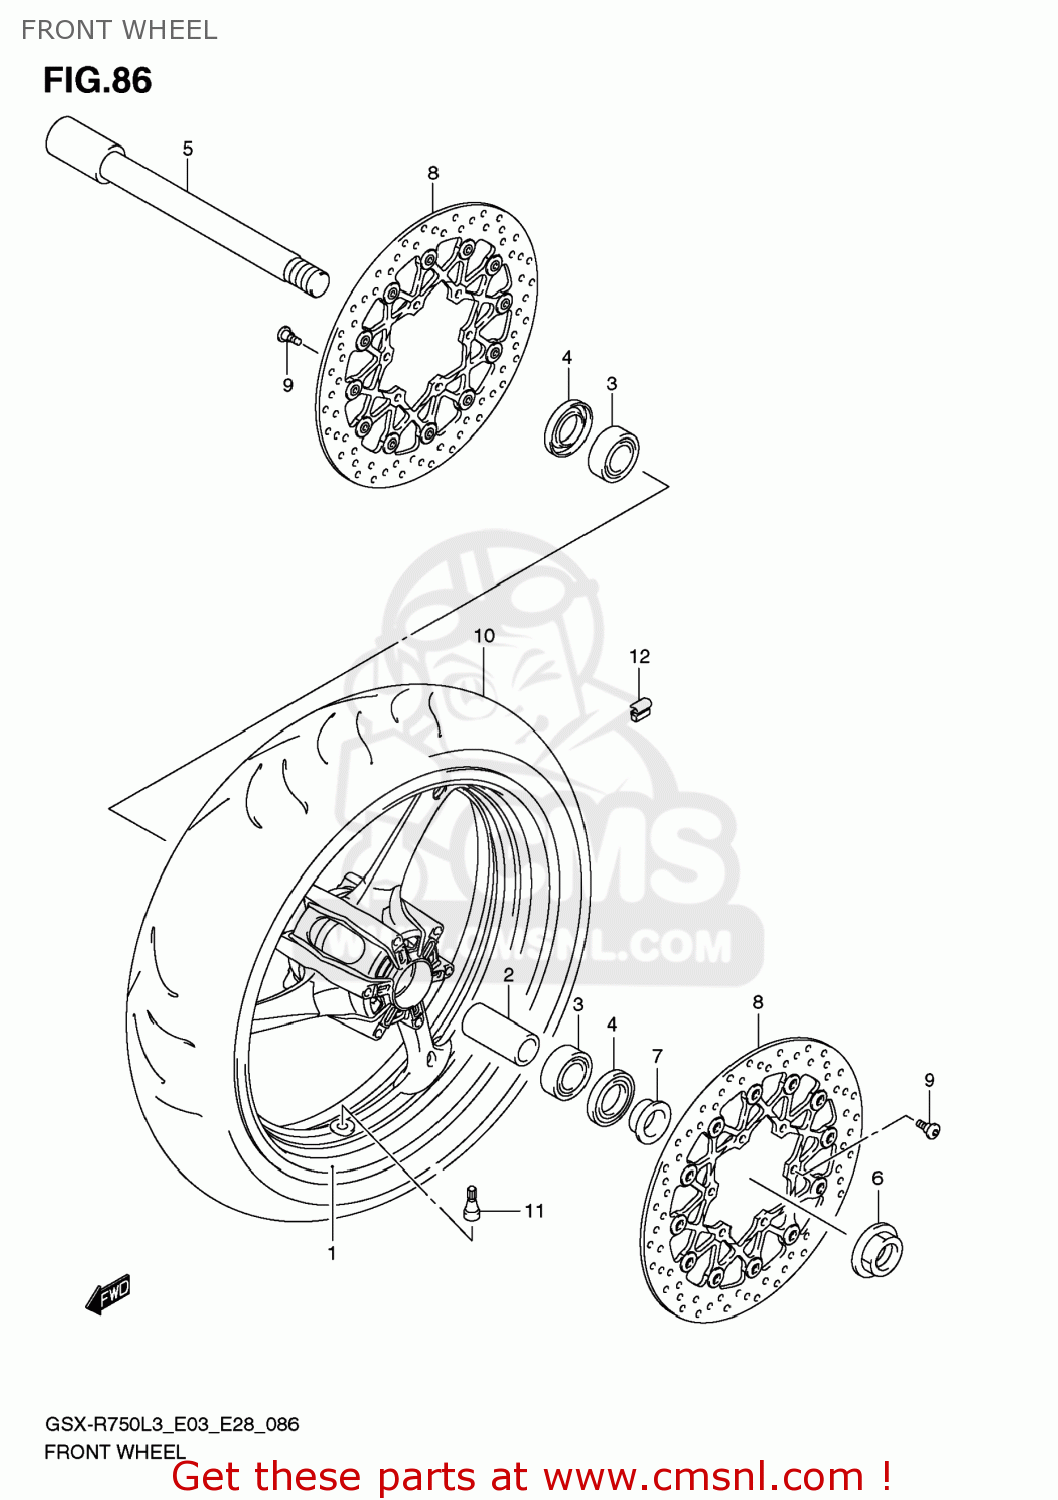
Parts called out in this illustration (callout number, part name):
1	WHEEL,FR(17M/CXMT3.50)
2	SPACER,FR HUB BEARING
3	BEARING(22X44X12)
4	SEAL,OIL(28X44X7.5)
5	AXLE,FR
6	NUT,RR SHOCK ABS BRACKET
7	SPACER,FR AXLE,L
8	DISC,FR BRAKE
9	BOLT(6X21)
10	TIRE,FR
11	VALVE ASSY,WHEEL RIM(TR412)
12	BALANCER,WHEEL(10G)
